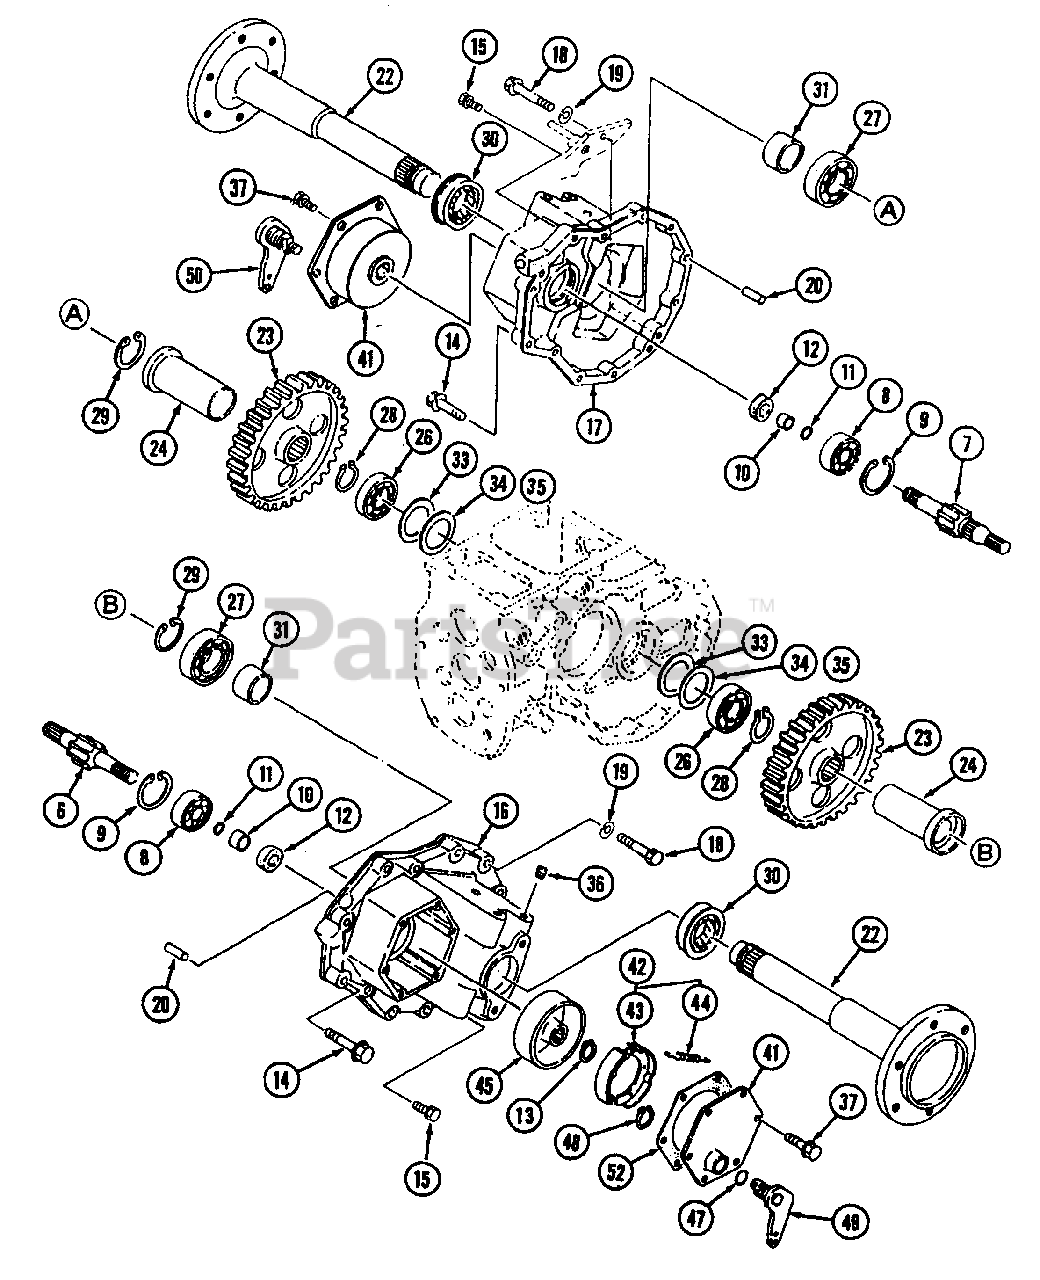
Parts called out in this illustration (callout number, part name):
43	Shoe, Brake
44	Spring
49	Cam Brake, L.H.
50	Cam Brake, R.H.
